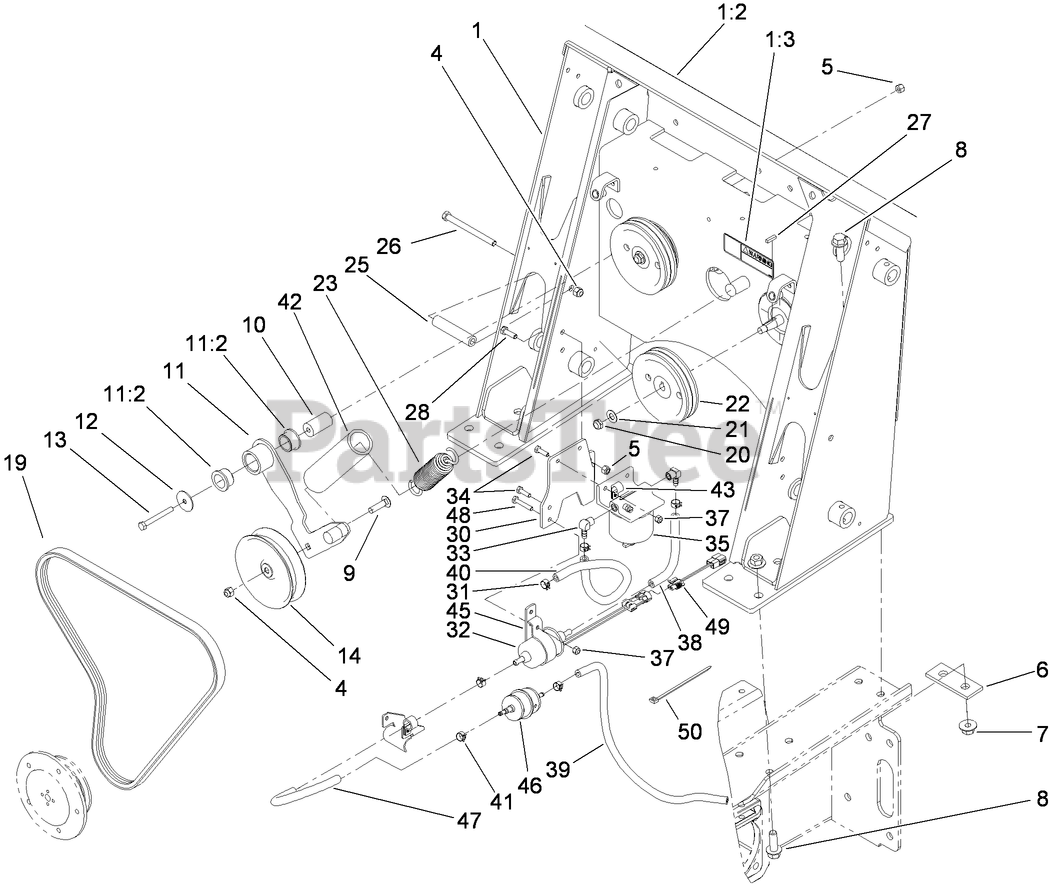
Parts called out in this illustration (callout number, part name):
1	LOADER TOWER ASM
1:2	DECAL-PANEL, CONTROL
1:3	DECAL-WARNING
4	NUT-LOCK, NI
5	NUT-LOCK, NI
6	PLATE-STIFFENER
7	NUT-LOCK, FLANGE
8	SCREW-HHF
9	SCREW-CARR
10	SPACER-MOUNTING
11	IDLER ARM ASM
11:2	BUSHING-FLANGE
12	WASHER-FLAT
13	SCREW-HH
14	PULLEY-IDLER
19	V-BELT
20	NUT-LOCK, NI
21	WASHER-FLAT
22	PULLEY
23	SPRING-EXTENSION
25	TUBE-SPACER
26	SCREW-HH
28	SCREW-HH
30	BRACKET-PUMP, FUEL
31	CLAMP-HOSE
32	PUMP-FUEL
33	FITTING-ELBOW
34	SCREW-HH
35	SEPARATOR-FILTER / WATER
37	NUT-LOCK, NI
38	HOSE-FUEL
39	HOSE-FUEL
40	HOSE-LP
41	CLAMP-HOSE
42	RETAINER-SPRING
43	CLAMP-R
45	BRACKET-PUMP, FUEL
46	FILTER-INLINE
47	HOSE-FUEL
48	SCREW-HH
49	HARNESS-WIRE
50	TIE-CABLE
